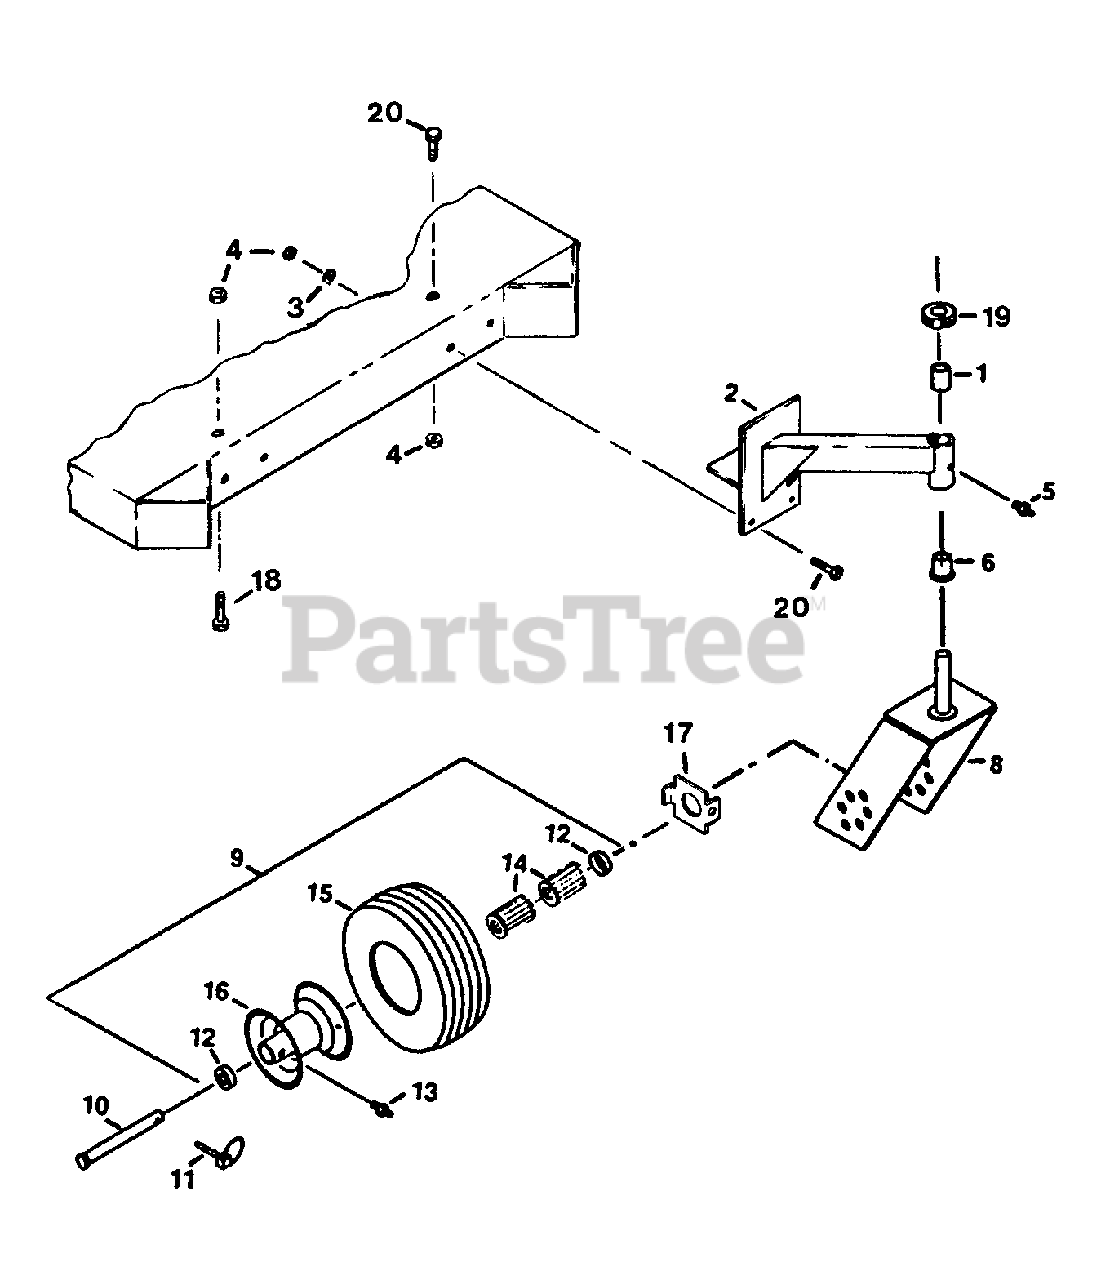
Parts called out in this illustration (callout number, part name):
1	Straight Bearing
2	Caster Arm w/Brgs (P/N 76514 & 76515)
3	3/8" Std. Flat Washer
4	3/8"-16 Nyloc Hex Nut
5	1/8" NPT Straight Zerk
6	Flange Thrust Bearing
9	Tire Assy. Complete
10	Axle
11	3/16" Dia. Linch Pin
12	1-1/2" I.D. Wheel Side Cap
12	1-5/8" I.D. Wheel Side Cap
13	1/16" NPT Straight Zerk
14	Roller Bearing
15	Tire
16	Rim w/Valve, Cap, & Zerk
17	Tab Washer
18	3/8"-16x1-3/4" Hex Hd. Tap Bolt
19	7/8" Clamp Collar
20	3/8"-16x1" Hex Hd. Cap Screw-Grade 5
